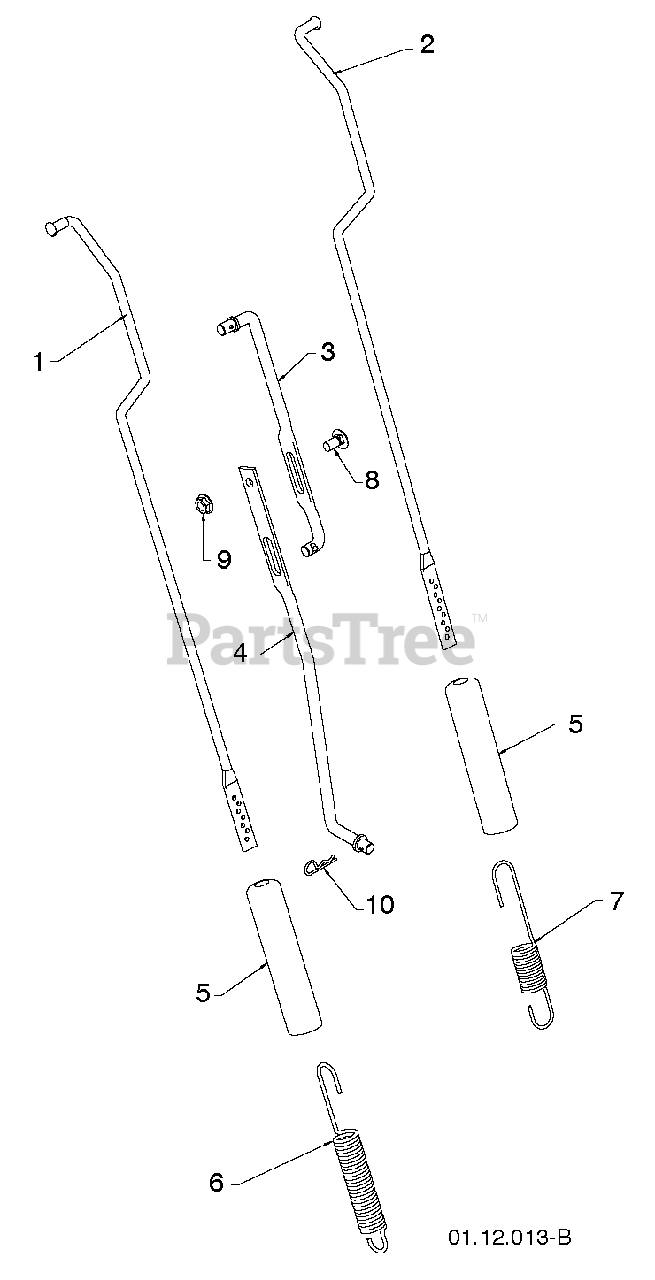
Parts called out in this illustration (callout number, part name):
1	ROD.IMPELLER
2	ROD.TRACTION
3	ROD, UPPER SPEED CONTROL
4	ROD, LOWER SPEED CONTROL.SNOW
5	SLEEVE, SPRING
6	SPRING.CONTROL.ROD.SNOW
7	SPRING.TRACTION.ROD.SNOW
8	BOLT
9	NUT.FLANGE.5/16
10	SPRING RETAINER
